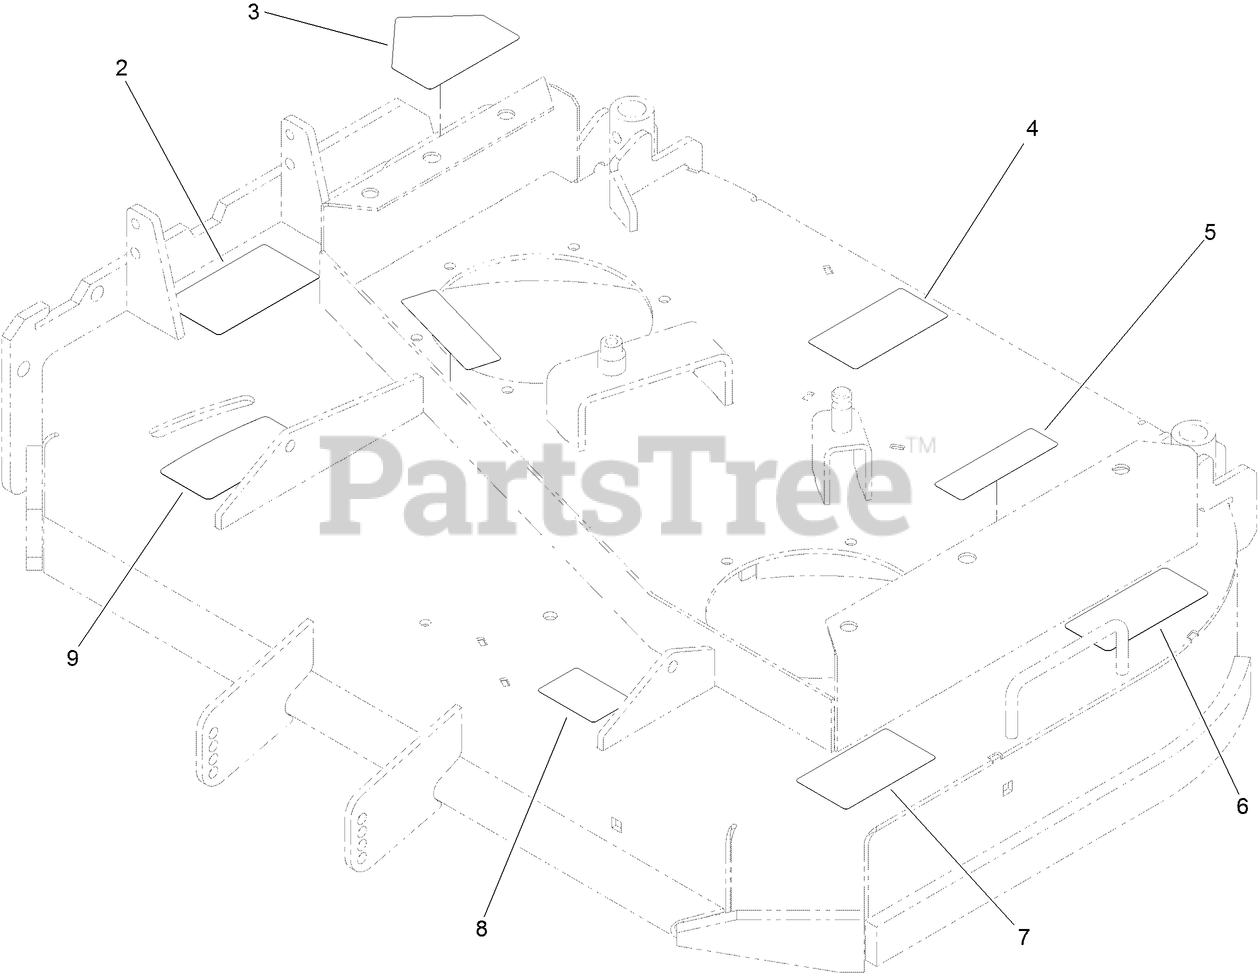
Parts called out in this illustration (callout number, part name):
2	DECAL-DANGER
3	DECAL-DANGER
5	DECAL-MISSING, COVER
6	DECAL-TORQUE, BLADE BOLT
7	DECAL-DANGER
8	DECAL-SCALP, ANTI
9	DECAL-ADJUSTMENT, BAFFLE
